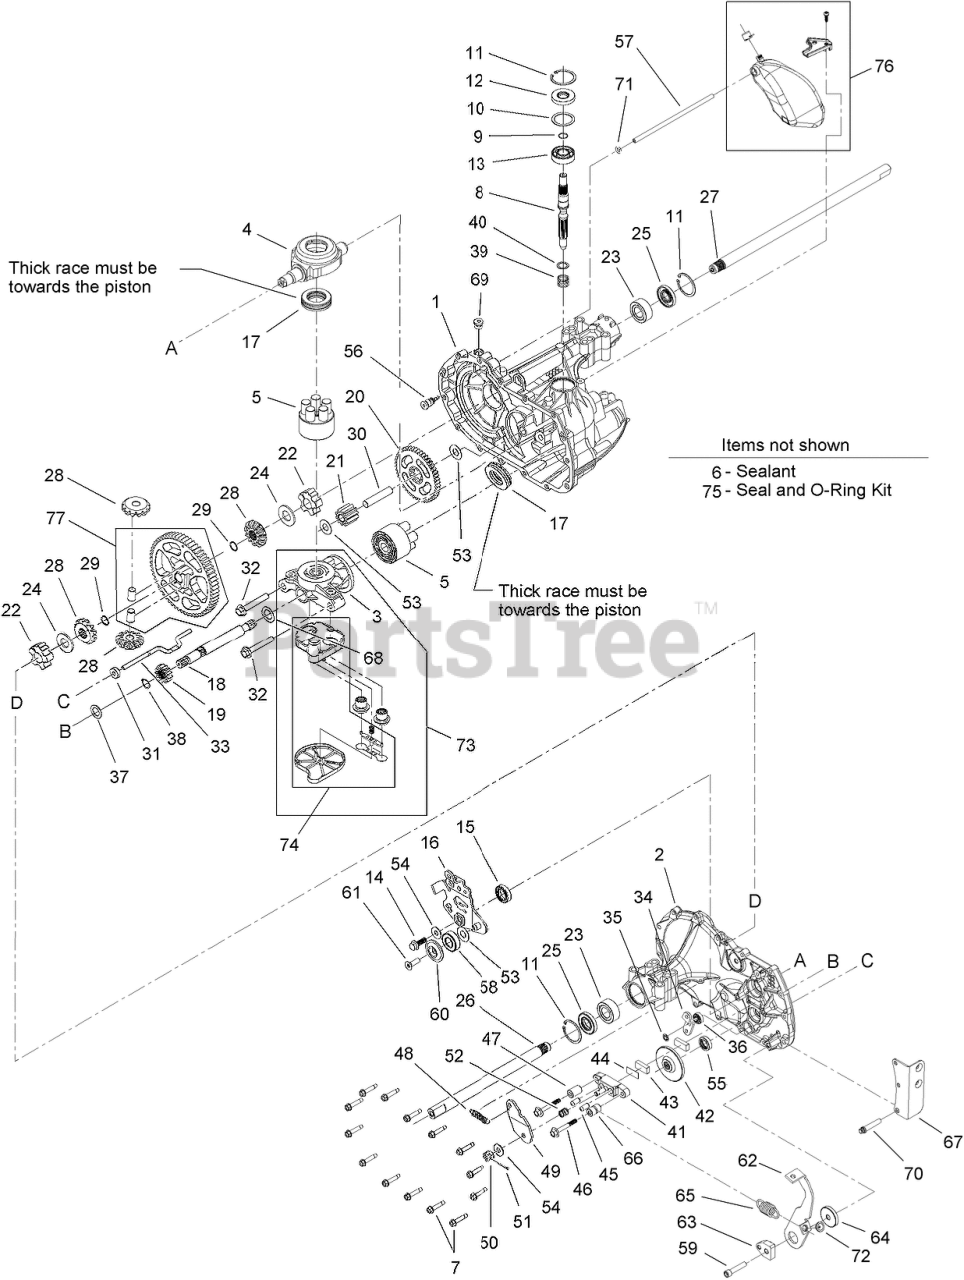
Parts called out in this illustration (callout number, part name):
1	MAIN HOUSING ASM
2	SIDE HOUSING ASM
3	CENTER SECTION ASM
4	SWASHPLATE-TRUNNION
5	CYLINDER BLOCK KIT
7	SCREW-HHF
8	SHAFT-INPUT
9	RING-RETAINING
10	SPACER
11	RING-RETAINING
12	SEAL-LIP
13	BEARING-BALL
14	SCREW-HF
15	SEAL-LIP
16	CONTROL-ARM
17	BEARING-THRUST
18	Shaft-Motor
19	GEAR-PINNION, 13T
20	GEAR-10T/48T
21	GEAR-JACKSHAFT, 10T
22	BEARING-SLEEVE
23	BEARING-SLEEVE, OUTBOARD
24	WASHER
25	SEAL-LIP
26	AXLE-SHAFT
27	AXLE-SHAFT
28	MITER GEAR KIT
29	RING-RETAINING, SPIRAL
30	PIN-JACKSHAFT
31	MAGNET-RING
33	ROD-ACTUATOR, BYPASS
34	ARM-BYPASS
35	RING-RETAINING
36	SEAL-LIP
37	WASHER-FLAT
38	RING-RETAINING
39	SPRING-BLOCK
40	WASHER-THRUST
41	YOKE-BRAKE
42	ROTOR-BRAKE
43	PUCK-BRAKE
44	PUCK-PLATE
45	PIN-BRAKE
46	SCREW-HF
47	SPACER
48	SPRING KIT
49	BRAKE-ARM
50	NUT-CASTLE
51	PIN-COTTER
52	SPRING-BRAKE, ANTI DRAG
53	WASHER
54	WASHER-PIVOT
55	SEAL-OIL
56	FITTING-SAE
57	HOSE-EXPANSION, TANK
58	BEARING
60	SPACER-LOCATING
61	SCREW-COUNTERSUNK
62	RETURN-ARM
63	PUCK-ADJUSTING
64	WASHER-FLAT
65	SPRING-EXTENSION
66	SPACER
67	BRACKET-TORQUE
68	WASHER
69	PLUG-THREAD, STRAIGHT
70	SCREW-TTH
71	O-RING
72	GUIDE-SPRING
73	CENTER SECTION FILTER BYPASS ASM
74	FILTER ASM
76	Expansion Tank Kit
77	60T BULL GEAR DIFFERENTIAL KIT (W/PINS)
